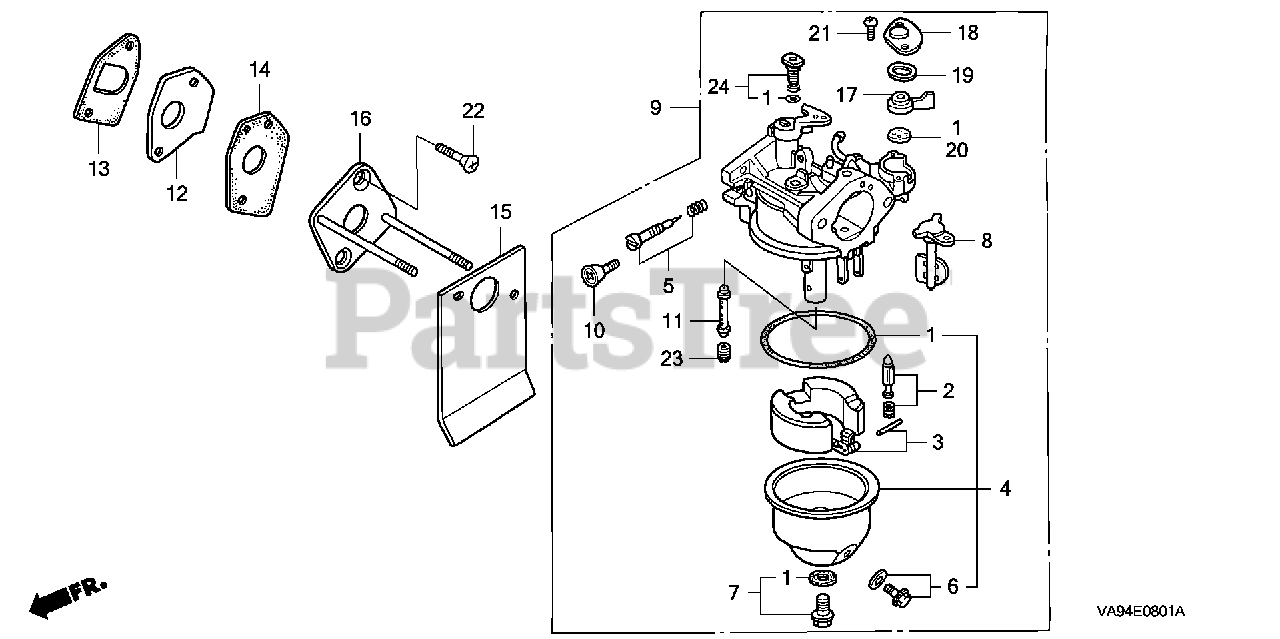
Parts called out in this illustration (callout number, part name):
1	GASKET SET
2	VALVE SET, FLOAT
4	CHAMBER SET, FLOAT
5	SCREW SET, PILOT
6	SCREW SET, DRAIN
7	SCREW SET
9	CARBURETOR ASSY. (BF07A C)
10	SCREW, THROTTLE STOP
11	NOZZLE, MAIN
12	INSULATOR, CARBURETOR
13	GASKET, INSULATOR
14	GASKET, CARBURETOR
15	GASKET, CARBURETOR
16	PLATE, CARBURETOR JOINT
17	LEVER, VALVE
18	PLATE, LEVER SETTING
19	SPRING, PETCOCK LEVER
20	GASKET, PETCOCK
21	SCREW, PAN (3X6)
21	SCREW, PAN (3X8)
22	SCREW, FLAT (3X6)
23	JET, MAIN (#55)
23	JET, MAIN (#58)
23	JET, MAIN (#60)
24	JET SET, PILOT (#35)
